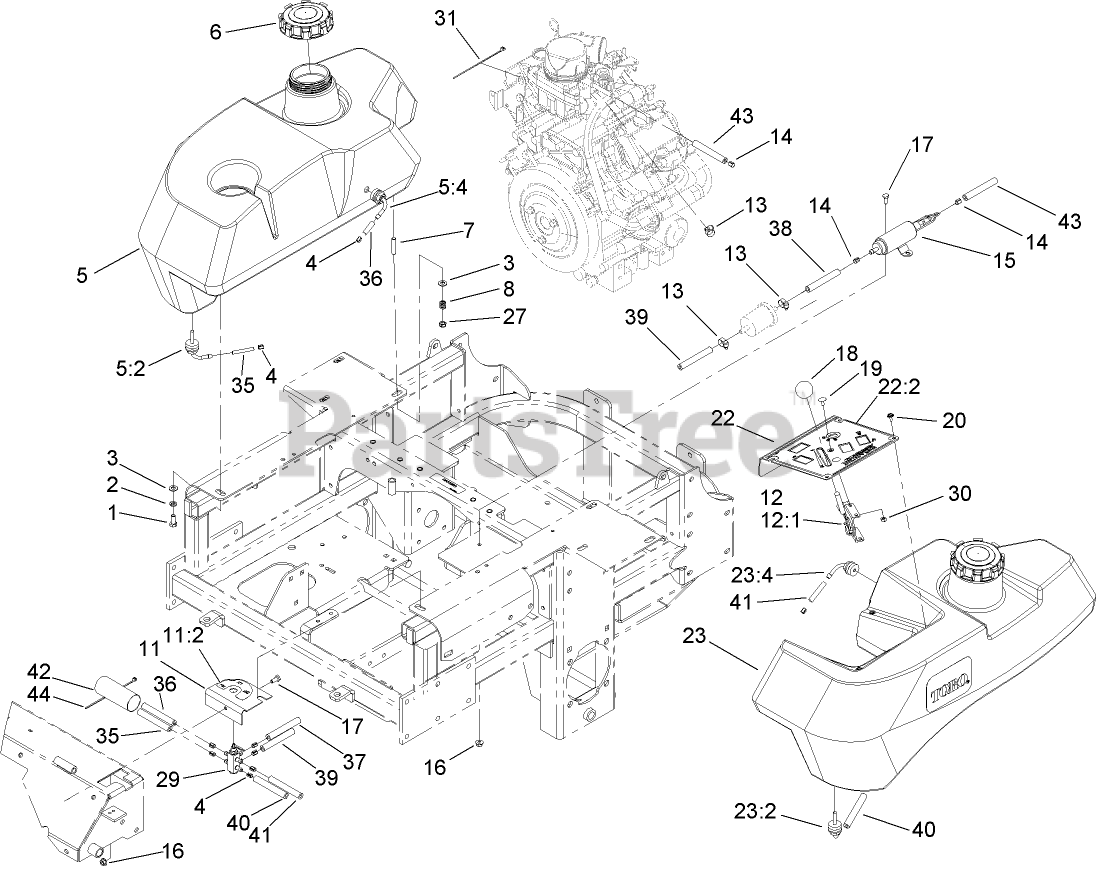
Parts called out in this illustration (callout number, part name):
1	SCREW-HH
2	WASHER-LOCK
3	WASHER-PLAIN
4	CLAMP-HOSE, FUEL
5	TANK-FUEL, RH
5:2	FITTING-FUEL, BULKHEAD
5:4	Fitting-Fuel, Bulkhead
6	CAP-FUEL, GAS
8	SPRING-TANK, FUEL
11	FUEL VALVE BRACKET ASM
11:2	DECAL-VALVE, FUEL
12	THROTTLE CONTROL ASM
12:1	LEVER-THROTTLE
13	CLAMP-WORM
14	CLAMP-HOSE, FUEL
15	PUMP-FUEL
16	NUT-HF
17	SCREW-HH
18	KNOB-BALL
19	BOLT-CARR
20	SCREW-PPH
22	CONTROL PANEL ASM
22:2	DECAL-CONTROL PANEL
23	TANK-FUEL, LH
23:2	FITTING-FUEL, BULKHEAD
23:4	Fitting-Fuel, Bulkhead
27	NUT-LOCK, NI
29	VALVE-FUEL, DUAL FLOW
30	NUT-LOCK, NI
31	TIE-CABLE
35	HOSE-FUEL
36	HOSE-FUEL
37	HOSE-FUEL
38	HOSE-FUEL
39	HOSE-FUEL
40	HOSE-FUEL
41	HOSE-FUEL
42	SLEEVE-FABRIC
43	HOSE-FUEL
44	TIE-CABLE
